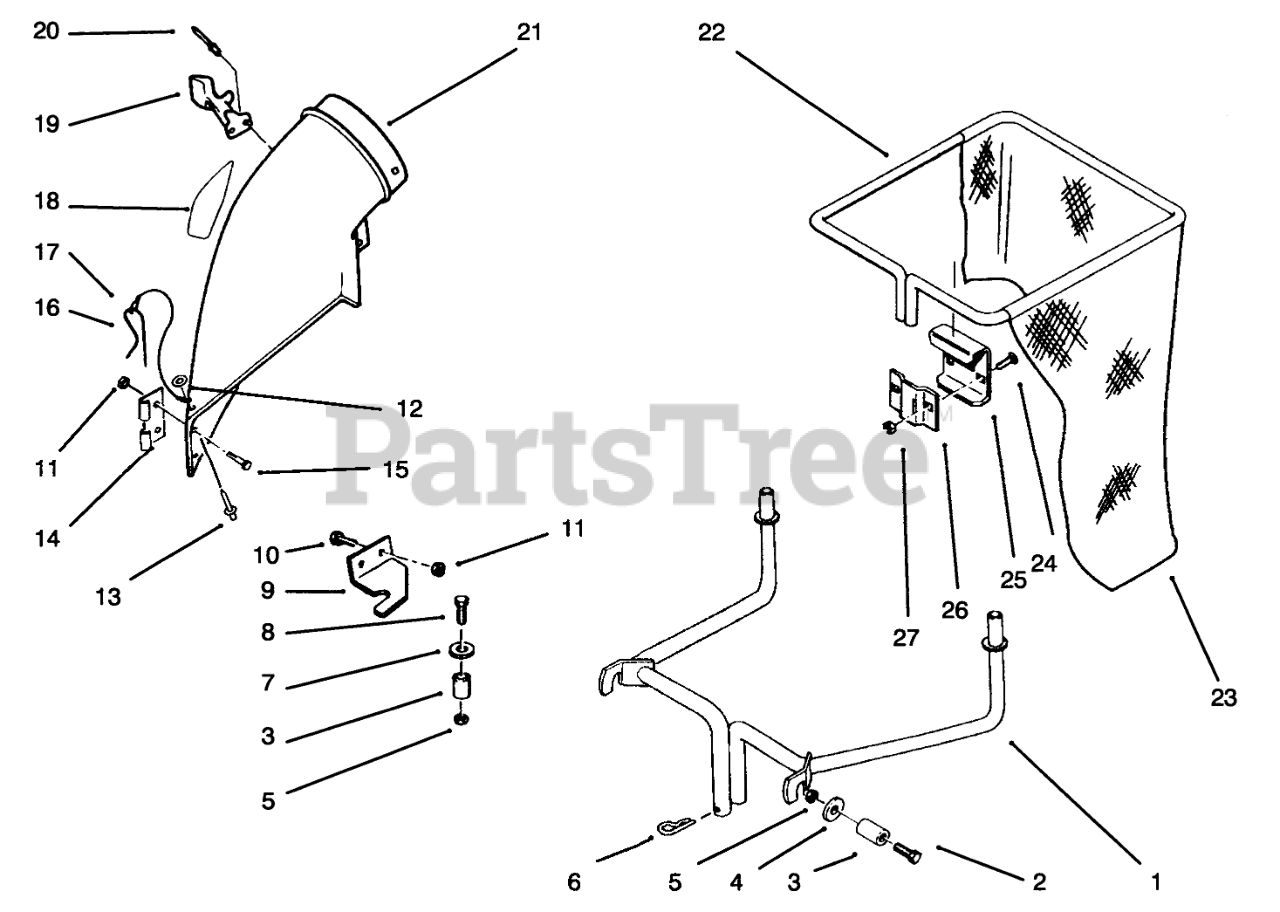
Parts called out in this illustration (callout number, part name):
1	Bracket-Quick Attach
2	SCREW-HH
3	SPACER
4	WASHER
5	NUT-LOCK, NI
6	Hairpin
7	WASHER-FLAT
8	SCREW-HH
9	LATCH-BAGGER ELBOW
10	Bolt
11	NUT-LOCK, NI
12	Washer
13	RIVET-POP
14	BRACKET-MOUNTING, CHUTE
15	SCREW-HH
16	PIN-LOCKING, CHUTE
17	LANYARD
18	DECAL-ATTACH-A-MATIC
19	HANDLE ASM
20	RIVET-POP
21	Chute Assembly (Incl. Ref. #9-15, 17-20)
22	Bag Frame
23	Bag
24	BOLT-CARR
25	Bag Hanger
26	Clamp
27	NUT-LOCK, NI
